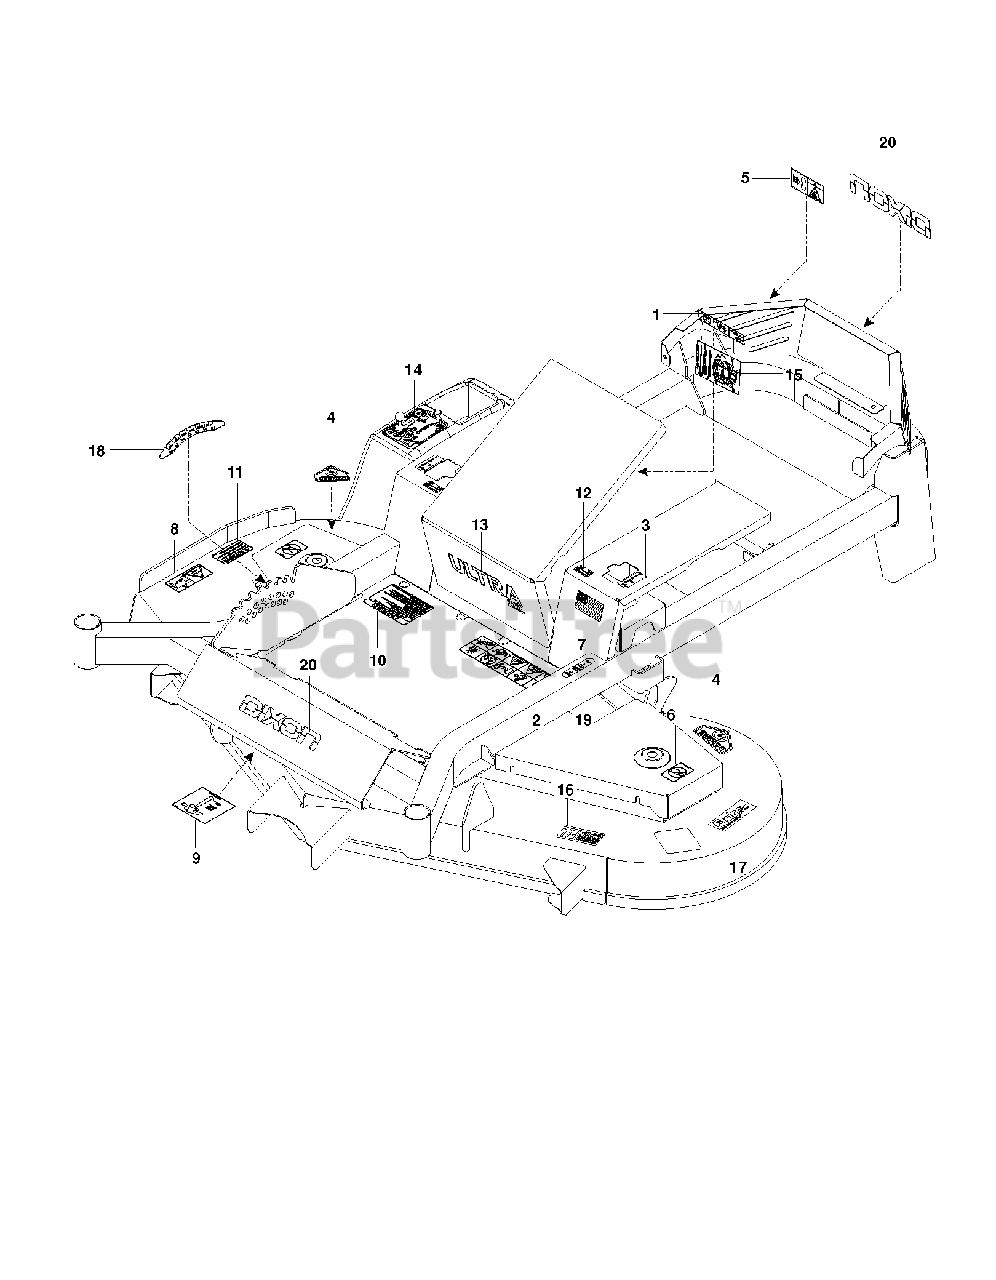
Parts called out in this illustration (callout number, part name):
2	DECAL, WARNING
3	DECAL, MOTION CONTROL
4	DECAL, CPSC
5	DECAL, BELT DRIVE
6	DECAL, NO STEP
7	DECAL, FLAG
8	DECAL, EURO SEVERING
9	DECAL, BELT ROUTING
10	DECAL, WARNING
11	DECAL, CAUTION
12	DECAL, TRACKING
13	DECAL, RAM ULTRA
15	DECAL, SERVICE
16	DECAL, TRI-FORCE
17	DECAL, FUSION
18	DECAL, HEIGHT ADJUSTMENT
19	DECAL, PARK BRAKE
